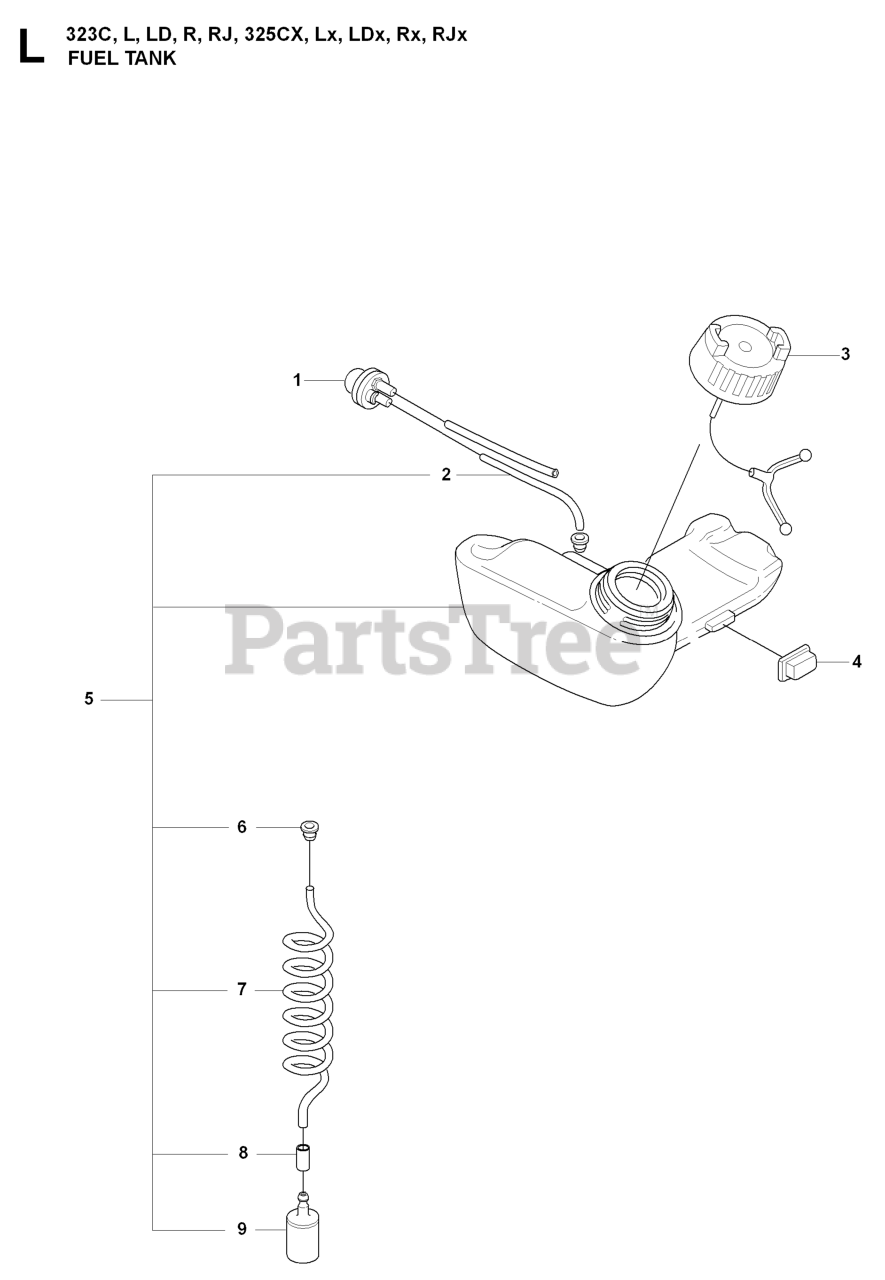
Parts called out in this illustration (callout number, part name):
1	AIR PURGE BUBBLE
2	HOSE.FUEL L=102
3	%FUEL CAP
6	FUEL TANK BUSHING
7	FUEL HOSE
8	HOSE CLAMP
9	RP FUEL FILTER
